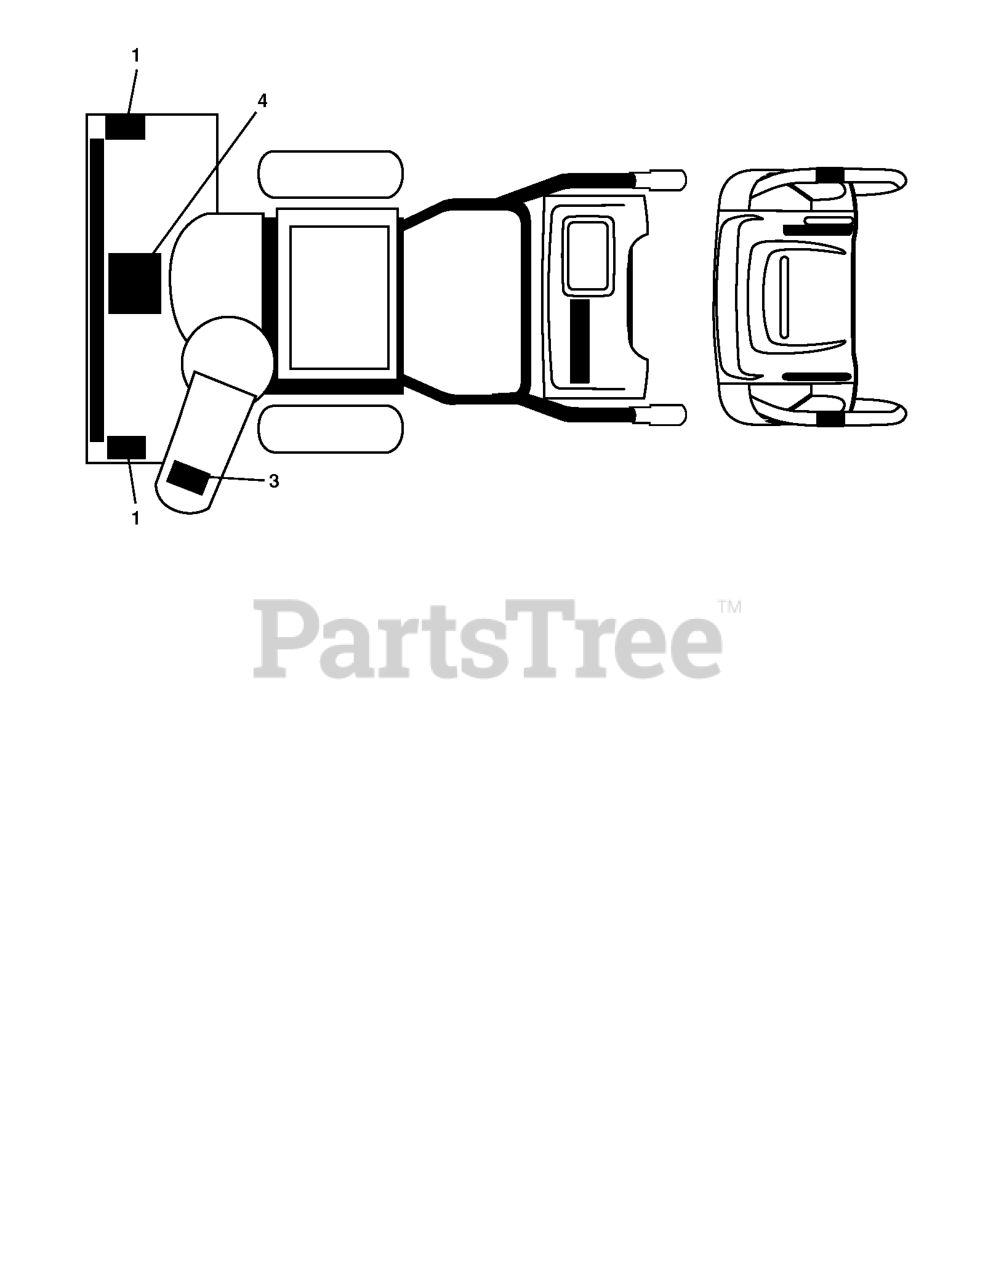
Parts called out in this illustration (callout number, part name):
1	DECAL.SNOWTHR.AUGER
3	DECAL.SNOWTHR.CHUTE.SAFETY
4	DECAL.SNOWTR.READ.OWN.MAN.E/F
